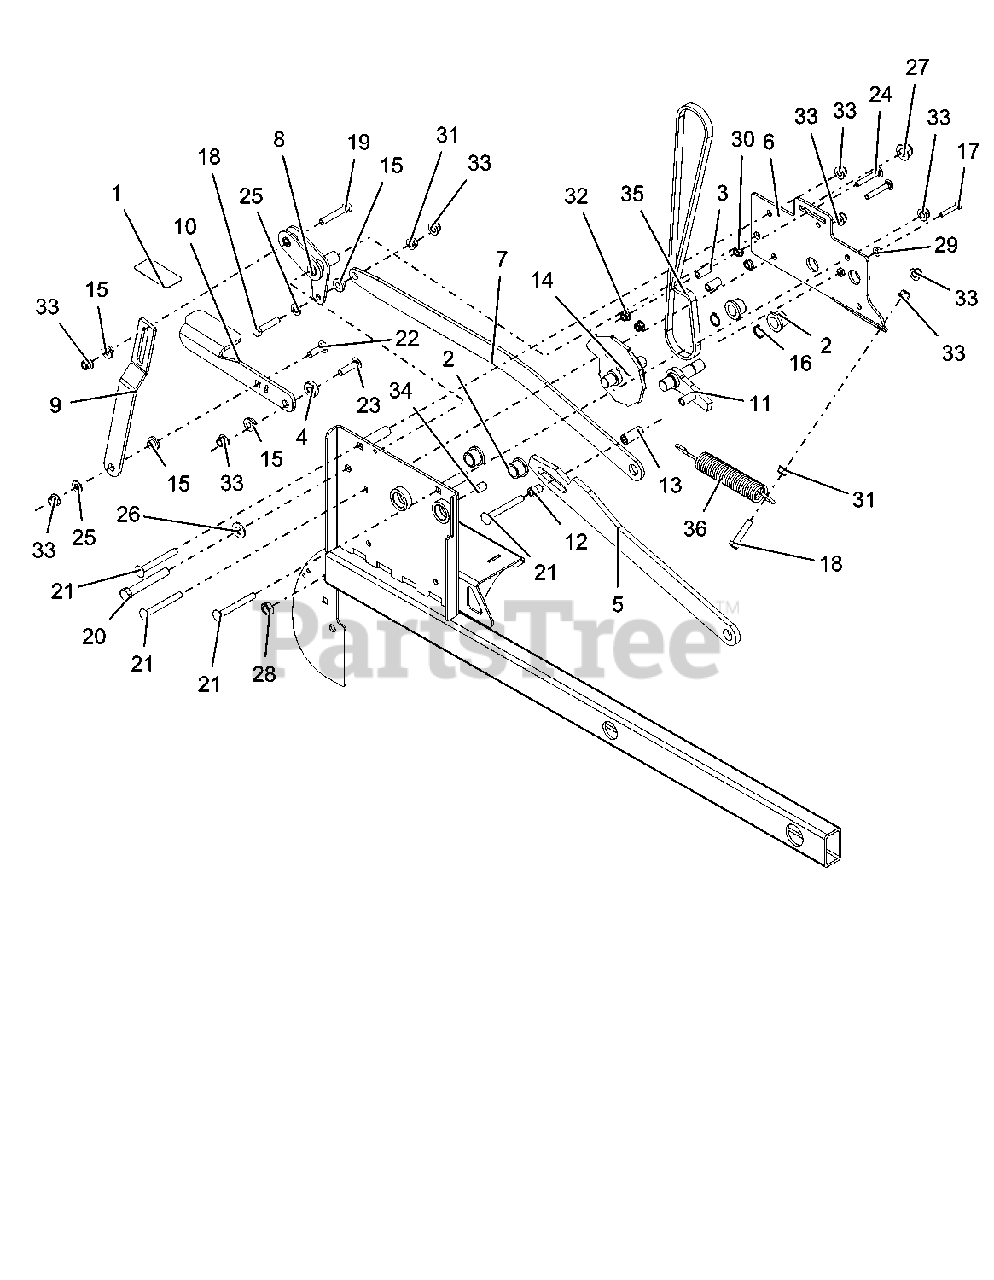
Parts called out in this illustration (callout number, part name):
1	GRIP, PEDAL 1.50 X 3.00
2	BUSHING, FLANGE .75X.75X1.0
3	SPACER .331 X .500 X 1.000
4	SPCR, .375 X 1.00 X .342
5	ARM, CAM CONTACT
6	WLDMT, CAM COVER
7	ARM, PEDAL
8	WLDMT, REAR PEDAL PIVOT
9	LINK, REAR PEDAL
10	PEDAL, DECK LIFT FOOT
11	WLDMT, TRAILER LOCK
12	BSHG, .375 X .75 X 1.00
13	SPCR, .375 X .75 X 1.00
14	WLDMT, 36 PS HOC CAM
15	BSHG-FLG .385X.500X.875X.406
16	RG-RTNG-EXT .689X.078
17	@BLT-HEX .25-20X1.50 GR5 YWZC
18	@BLT-HEX .38-16X1.75 GR5 YWZC
19	@BLT-HEX .38-16X2.25 GR5 YWZC
20	@BLT-HEX .50-13X3.50 GR5 YWZC
21	BLT-RDHDSQNK .38-16X3.25 GR5YZ
22	@BLT-RHDSSQNK .38-16X1.25 G5YZ
23	@BLT-RHDSSQNK .38-16X1.50 G5YZ
24	BLT-RDHDSQNKFT .31-18X2.0 G5YZ
25	@WSHR-FL-STL.406X.812X.065 YWZ
26	@WSHR-FL-STL.531X1.06X.095YWZC
27	@NUT-LK-NYL-FLG .50-13 YWZC
28	NUT-JAM .50-13 YWZC
29	@NUT-SPNLK-FLG .25-20 YWZC
30	@NUT-SPNLK-FLG .312-18 YWZC
31	@NUT-SPNLK-FLG .375-16 YWZC
32	@NUT-LK-NYL-FLG .31-18 YWZC
33	@NUT-LK-NYL-FLG .38-16 YWZC
34	BALL SPRING PLUNGER, .500-13
35	BELT, TIMING SHORT
36	SG-TENS .162X1.25X8.25 WLD 25
